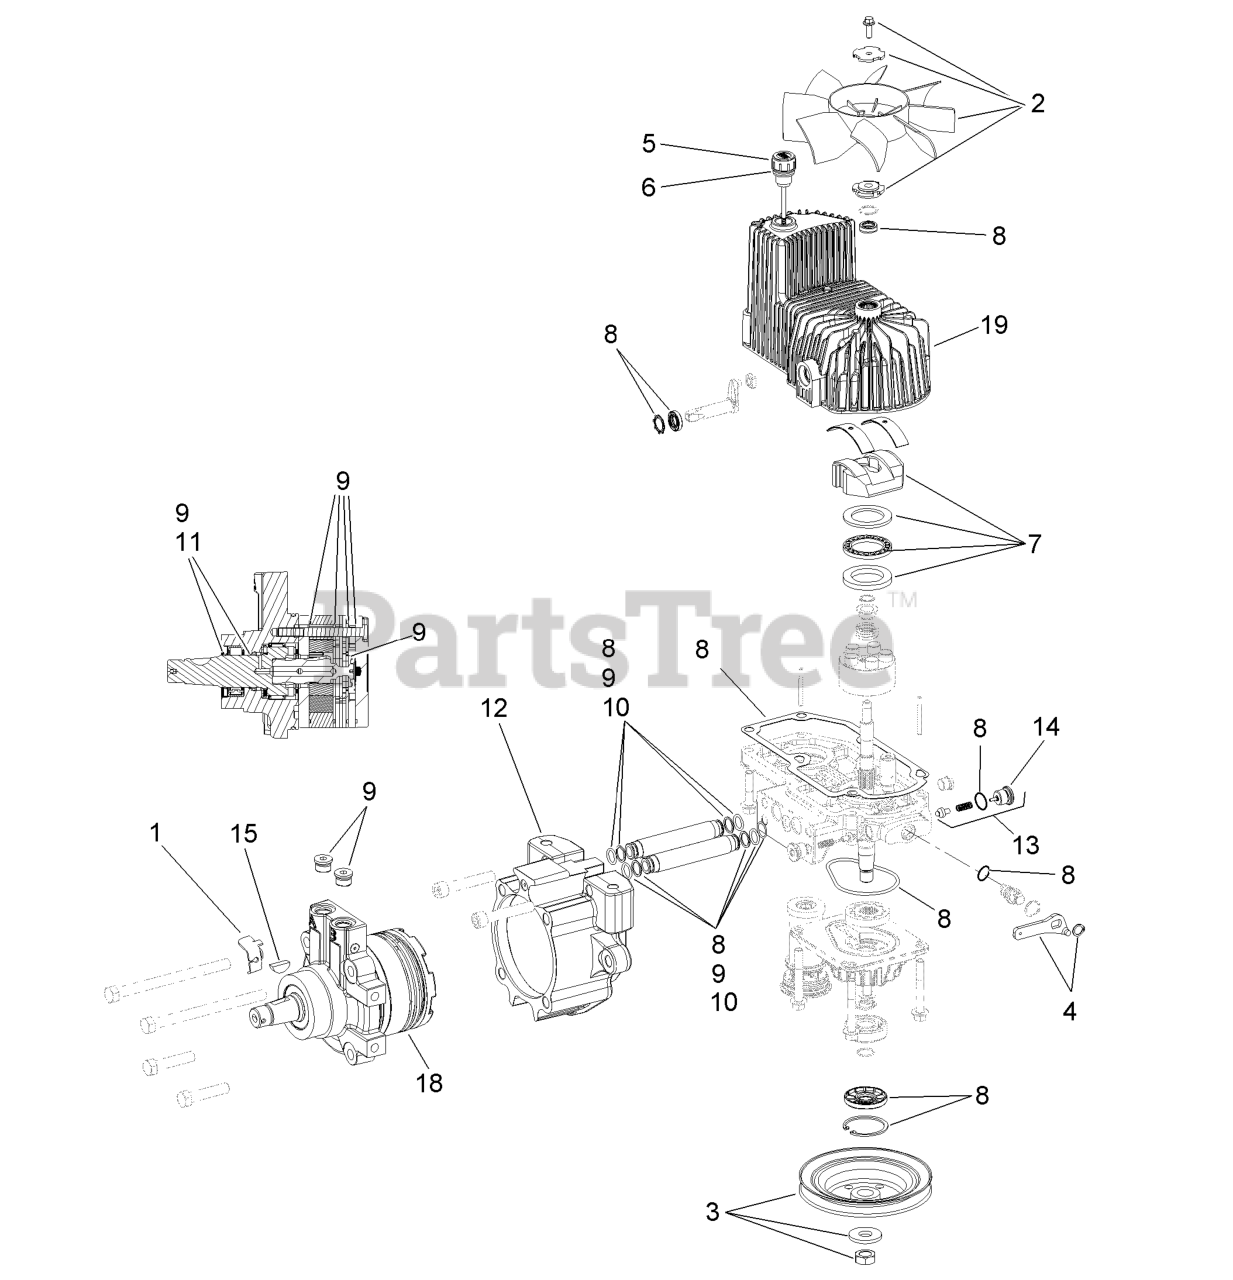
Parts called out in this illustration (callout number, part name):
1	BRACKET-ANCHOR, CABLE
2	FAN KIT
3	PULLEY KIT
4	HANDLE-BYPASS VALVE, HYDRO
5	DIPSTICK-HYDRO W/GASKET
6	GASKET-DIPSTICK, HYDRO
7	SWASH BLOCK KIT
8	PUMP SEAL KIT
9	MOTOR SEAL KIT
10	TUBE SEAL KIT
11	OUTPUT SHAFT SEAL KIT
13	CHECK VALVE ASM
14	PLUG-CHECK (W/O-RING)
15	KEY-WOODRUFF
19	HOUSING-HYDRO, LH
